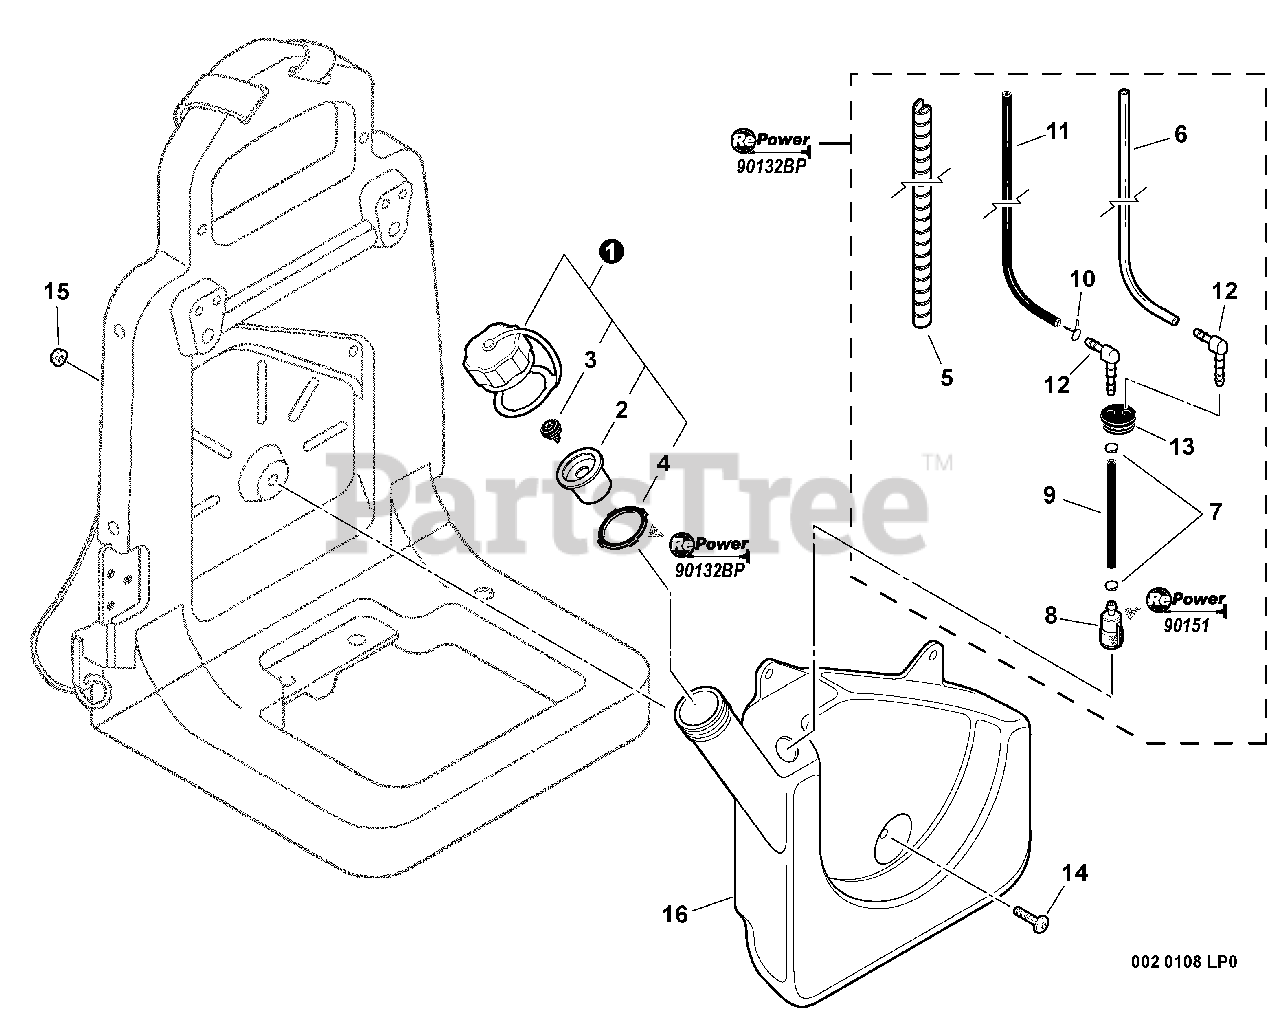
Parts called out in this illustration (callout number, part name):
1	CAP ASSY, FUEL
2	HOLDER, VENT
3	VENT ASSY
4	GASKET, FUEL CAP
5	TUBE, SPIRAL
6	PIPE, FUEL - 3×6×470 - CLEAR
7	CLIP Ø6.5 MM
8	FILTER, FUEL
9	PIPE, FUEL 3×6×280 MM
10	CLIP, SPRING Ø5.2
11	PIPE, FUEL - 3×5×470 - BLACK
12	CONNECTOR, PIPE
13	GROMMET, FUEL
14	SCREW 5×20
15	NUT, FLANGE M5
16	TANK, FUEL
17	FUEL SYSTEM KIT
18	TUNE-UP KIT - REPOWER
